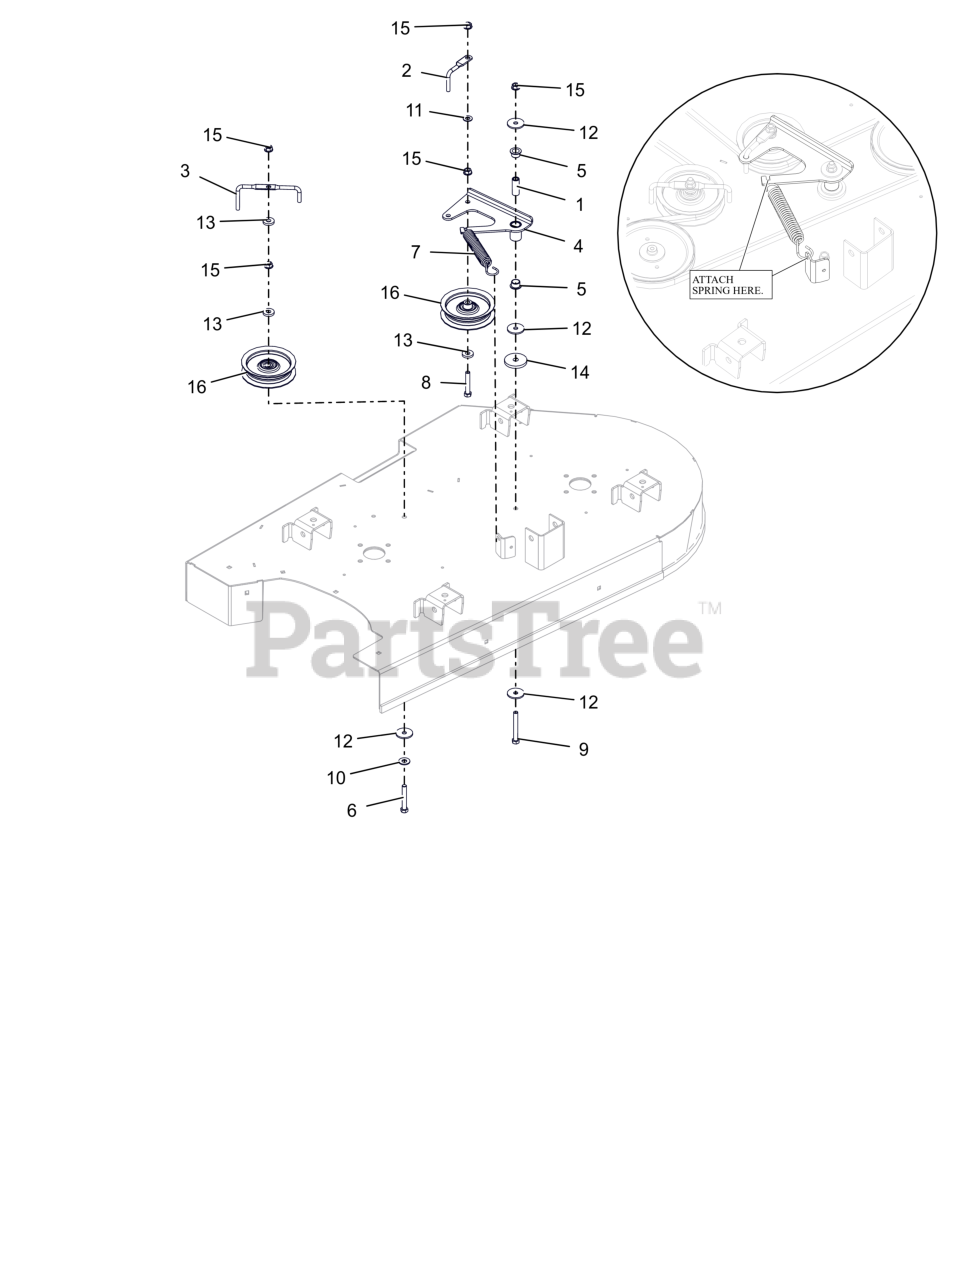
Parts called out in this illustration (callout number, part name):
1	SPACER, .375IDX.625ODX1.66 PM
2	WIREFORM-BELT FINGER
3	BELT FINGER
4	WLDMT, IDLER ARM (ORANGE)
5	BSHG-FLG, .625X.750X.500X1.00
6	BLT, HEX .38-16X2.50 G5 ZCC
7	SG-TENS .135X.98X6.0 WLD 62
8	BLT,HEX .38-16X2.25 G5 ZCC
9	BLT, HEX .38-16X3.00 G5 ZCC
10	WSHR,FLT .438X1.00X.083 ZCC
11	WSHR,FLT .406X.812X.065 ZCC
12	WSHR, FLT .380X1.50X.125 ZCC
13	WSHR, FLT .406X1.00X.188 ZCC
14	WSHR, FLT .469X2.00X.250 ZCC
15	NUT-LK-CTR-FLG .375-16 GF ZCC
16	IDLER, FLAT - 4.06" X .75"
